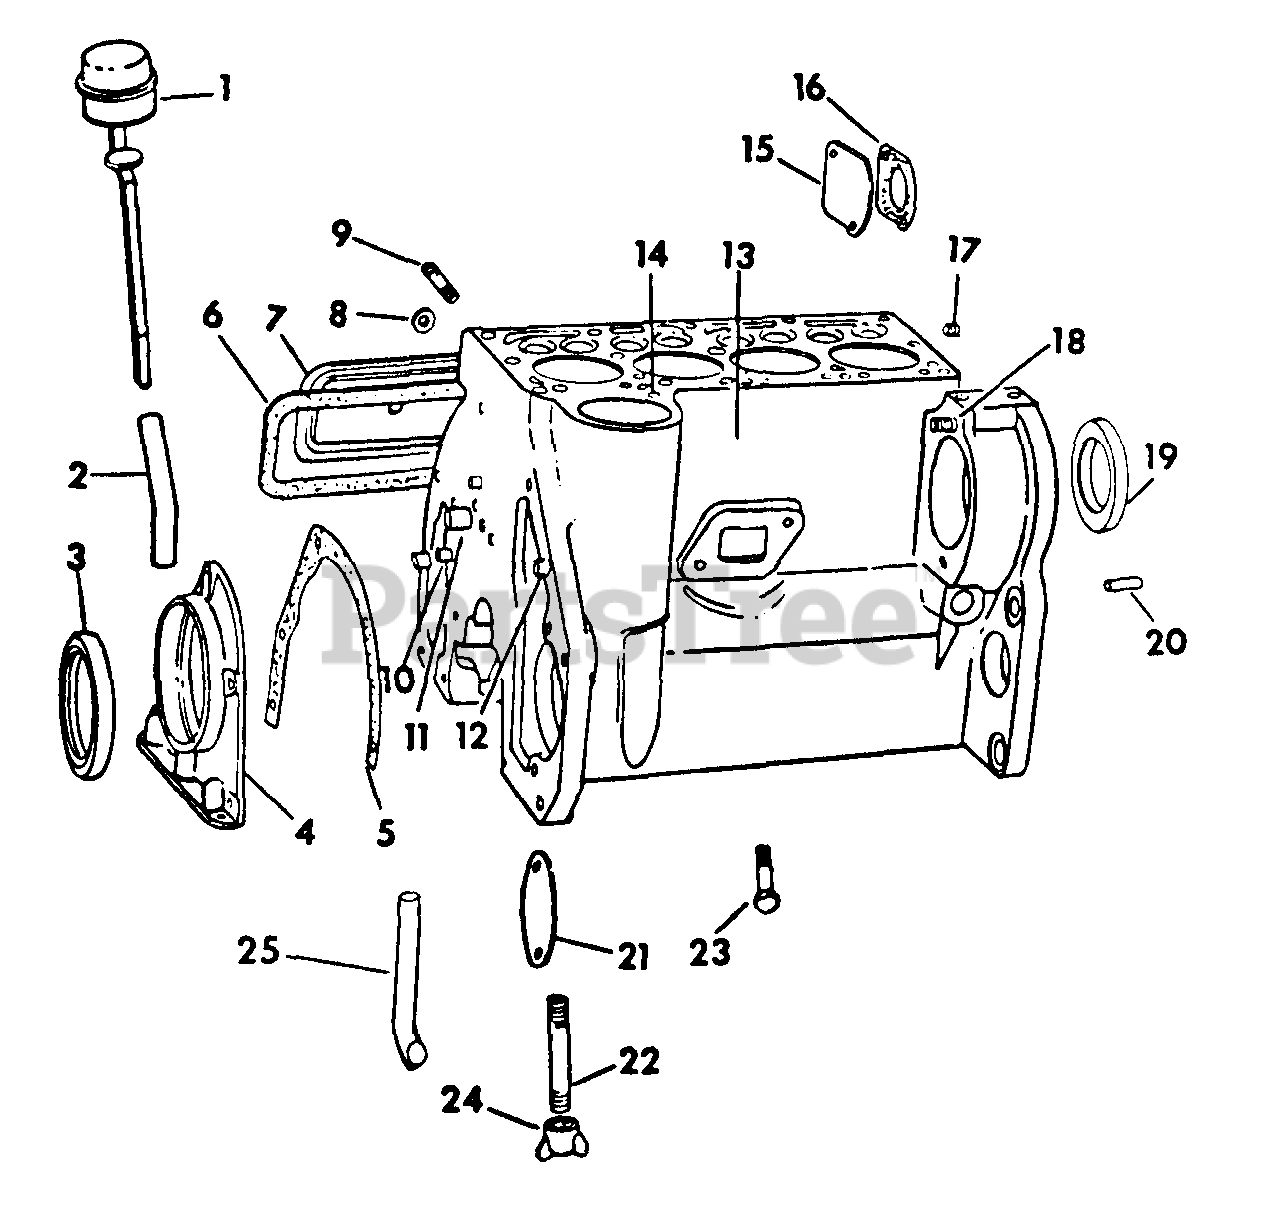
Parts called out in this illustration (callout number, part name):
1	GAUGE W/BREATHER CAP, OIL LEVEL
2	TUBE OIL FILLER AND BREATHER
3	SEAL, CRANKSHAFT REAR OIL
4	RETAINER W/SEAL
5	GASKET, CRANKSHAFT REAR OIL SEAL RETAINER
6	GASKET, VALVE TAPPET COVER
7	COVER, VALVE TAPPET
8	WASHER, VALVE TAPPET COVER BOLT
9	STUD, MANIFOLD
10	DOWEL, OIL PUMP BODY
11	SHAFT, OIL PUMP IDLER
12	DOWEL, CLUTCH HOUSING
13	CRANKCASE W/PISTONS AND RINGS ASSY
14	PLUG, 1/8-27 AUTO SQ-HD PIPE CRANKCASE OIL HOLE
15	COVER, HYD LIFT PUMP OPENING
16	GASKET, HYD LIFT PUMP OPENING COVER
17	PLUG, 1/4-18 AUTO SQ-SOC PIPE CRANKCASE OIL HOLE
18	STUD, MOUNTING DISTRIBUTOR DRIVE HOUSING
19	SEAL, MAGNETO DRIVE OIL
20	PIN, IDLER GEAR SHAFT LOCATING
21	COVER, STARTER PAD TRACTOR W/MOTOR - GENERATOR
22	NIPPLE, 3/8 X 5-7/8 PIPE OIL FILTER DRAIN
23	BOLT, CRANKCASE BEARING CAP
24	CAP, OIL FILTER DRAIN PIPE NIPPLE
25	NOT USED IN THIS APPLICATION
